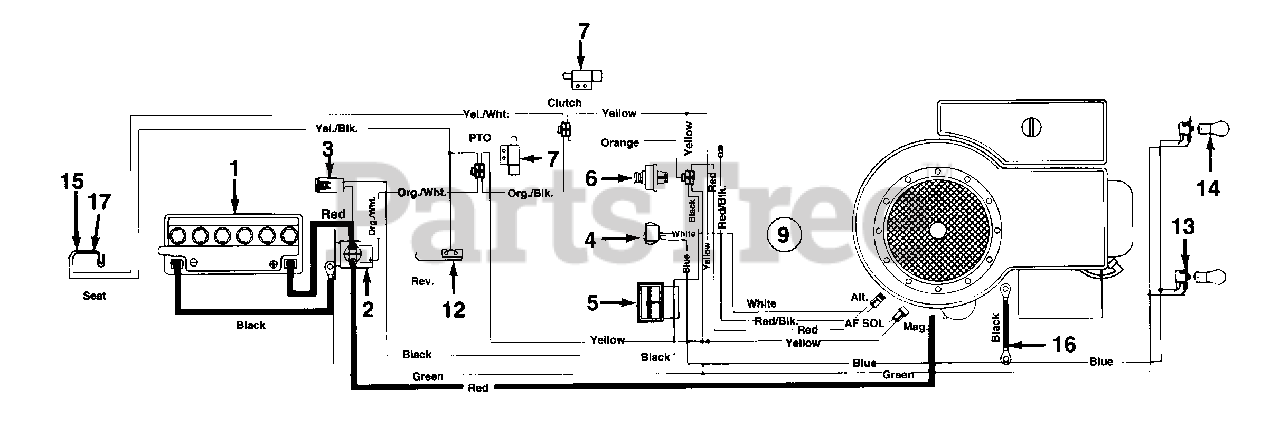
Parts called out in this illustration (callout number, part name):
1	Battery
2	Solenoid
3	Fuse 7.5 Amps
4	Light Switch
5	Ammeter
6	Ignition Switch
7	Safety Switch (Clutch)
9	Wire Harness
12	Safety Switch (Reverse)
13	Socket
14	Bulb (Headlight)
15	Safety Switch (Seat)
16	Ground Wire 7.5" Lg.
17	Safety Switch (Seat)
